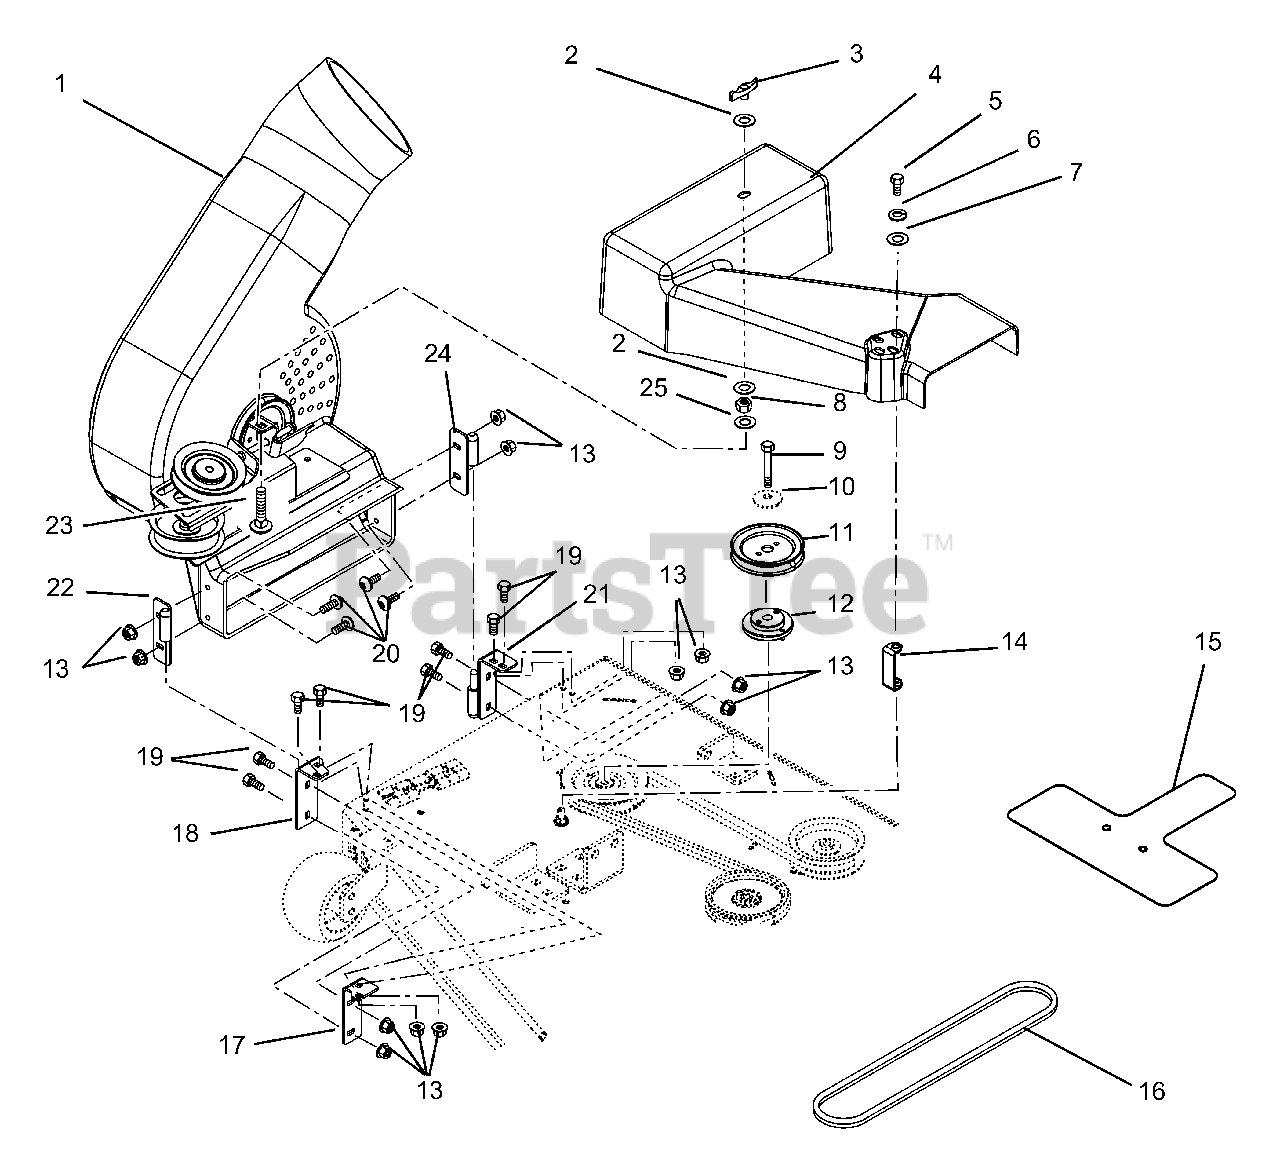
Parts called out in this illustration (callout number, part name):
1	BLOWER HSG W/DECAL
2	WSHR-FL-STL .380X1.50X.062 YWZ
3	KNOB - WING .312-18 UNC
4	BELT COVER W/DECAL
5	@BLT-HEX .38-16X.75 GR5 YWZC
6	@WSHR-LK .38X.094 REG YWZC
7	@WSHR-FL-STL.438X1.00X.083 YWZ
8	NUT- JAM .312-18 YWZC
9	BLT-HEX .38-16X1.75 GR8 M-EPYZ
10	WASHER, CUPPED SERRATED, .375
11	SHEAVE, 3.00 DIA.
11	SHEAVE, 4.00 DIA.
12	ASSEMBLY, SHEAVE ADAPTER
13	@NUT-LK-TOP-FLG .25-20 YWZC
14	SPACER, COVER
15	GUARD,FINGER
16	V-BELT, HA-WRAPPED
16	V-BELT, HA-RAW EDGE
17	BRACKET, FRONT
18	WELDMENT, FRONT MOUNT BRACKET
19	@BLT-HEX .25-20X.75 GR5 YWZC
20	SCR-MCH .25-20X.75 TXTR YWZC
21	WELDMENT, REAR MOUNT BRACKET
22	WELDMENT, HOUSING MOUNT RH
23	@BLT-RDHDSQNK .31-18X1.50 G5YZ
24	WELDMENT, HOUSING MOUNT LH
25	@WSHR-FL-STL.312X.734X.065 YWZ
